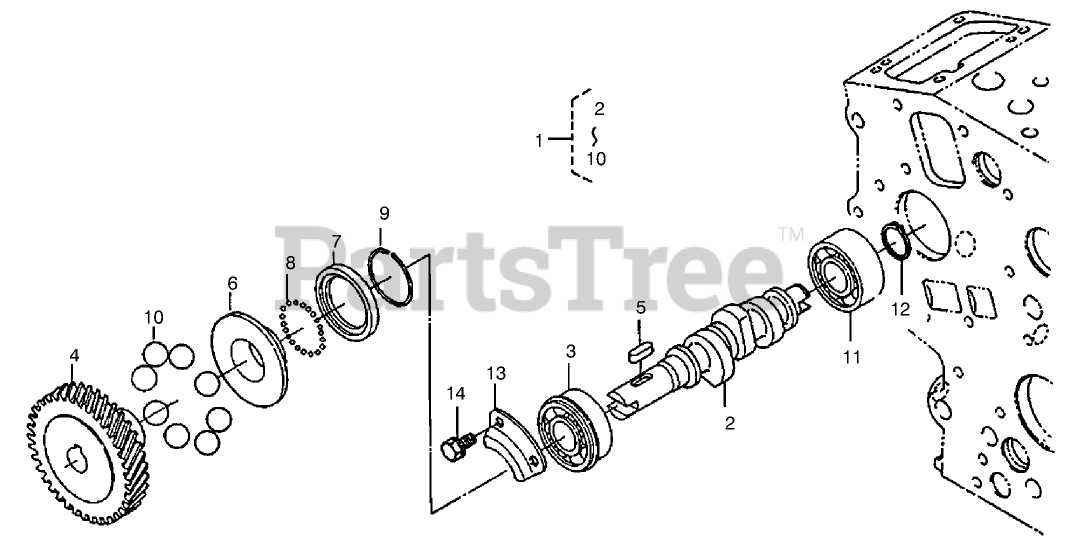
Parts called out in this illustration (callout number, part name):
1	FUEL CAMSHAFT ASM
2	CAMSHAFT
3	BEARING-BALL
4	GEAR-PUMP, INJECTION
5	KEY-FEATHER
6	SLEEVE-GOVERNOR
7	CASE-BALL, GOVERNOR
9	CIRC-CLIP
11	BEARING-BALL
12	CIRC-CLIP, EXTERNAL
13	STOPPER-FUEL, CAMSHAFT
